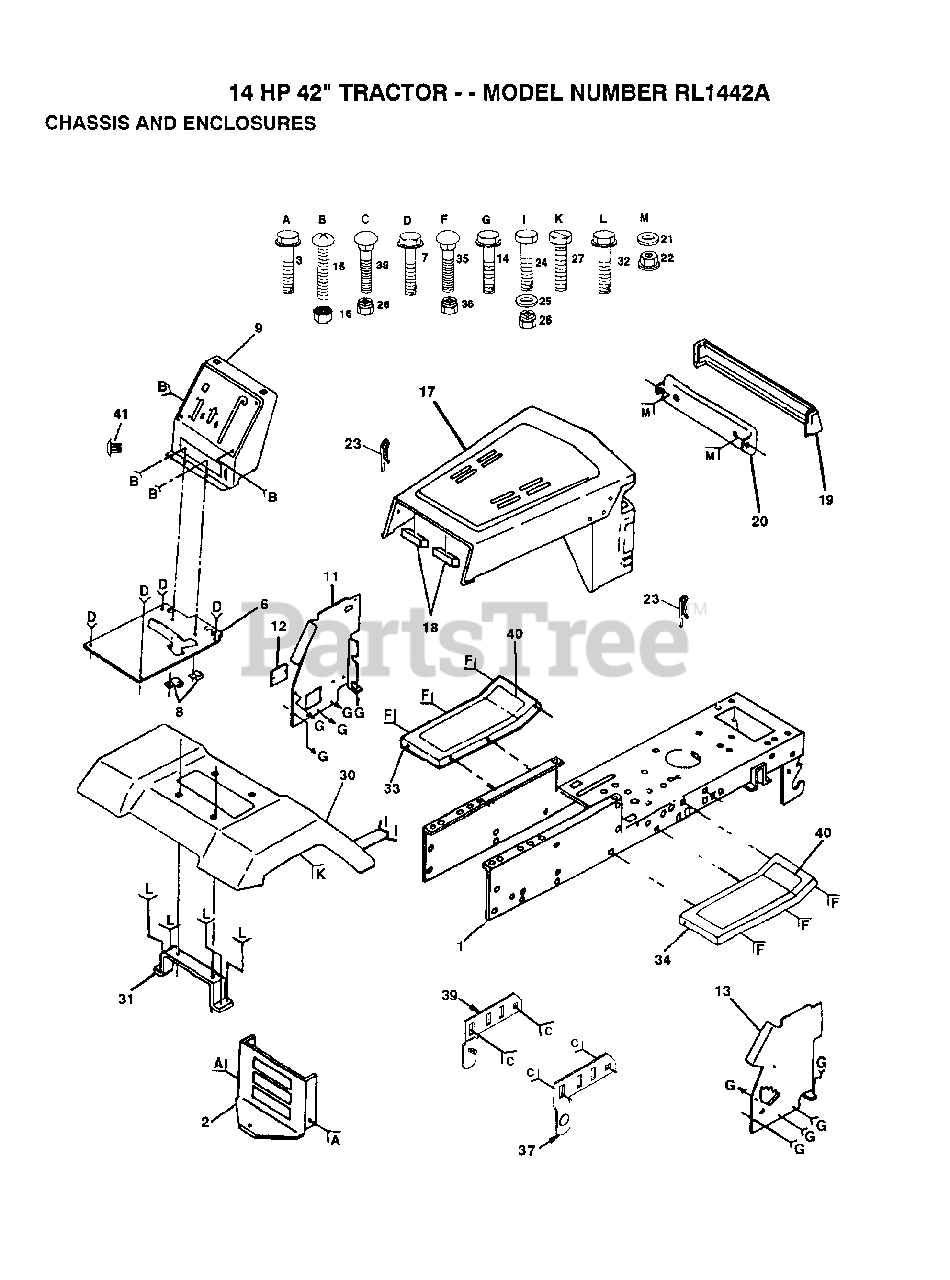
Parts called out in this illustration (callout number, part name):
3	SCREW
7	SCREW LT
8	CLIP T
11	PANEL DASH LH
12	COVER ACCESS
14	SCREW LT
15	SCREW
17	HOOD/GRILL ASM
21	WASHER PM
22	PAL NUT LT
23	SPRING.RETAINER
25	WASHER
27	SCREW LT
32	SCREW
35	BOLT
37	PIVOT BRKT RH
38	BOLT
39	PIVOT BRKT LH
40	"PAD,FOOTREST"
41	PLUG BUTTON T
